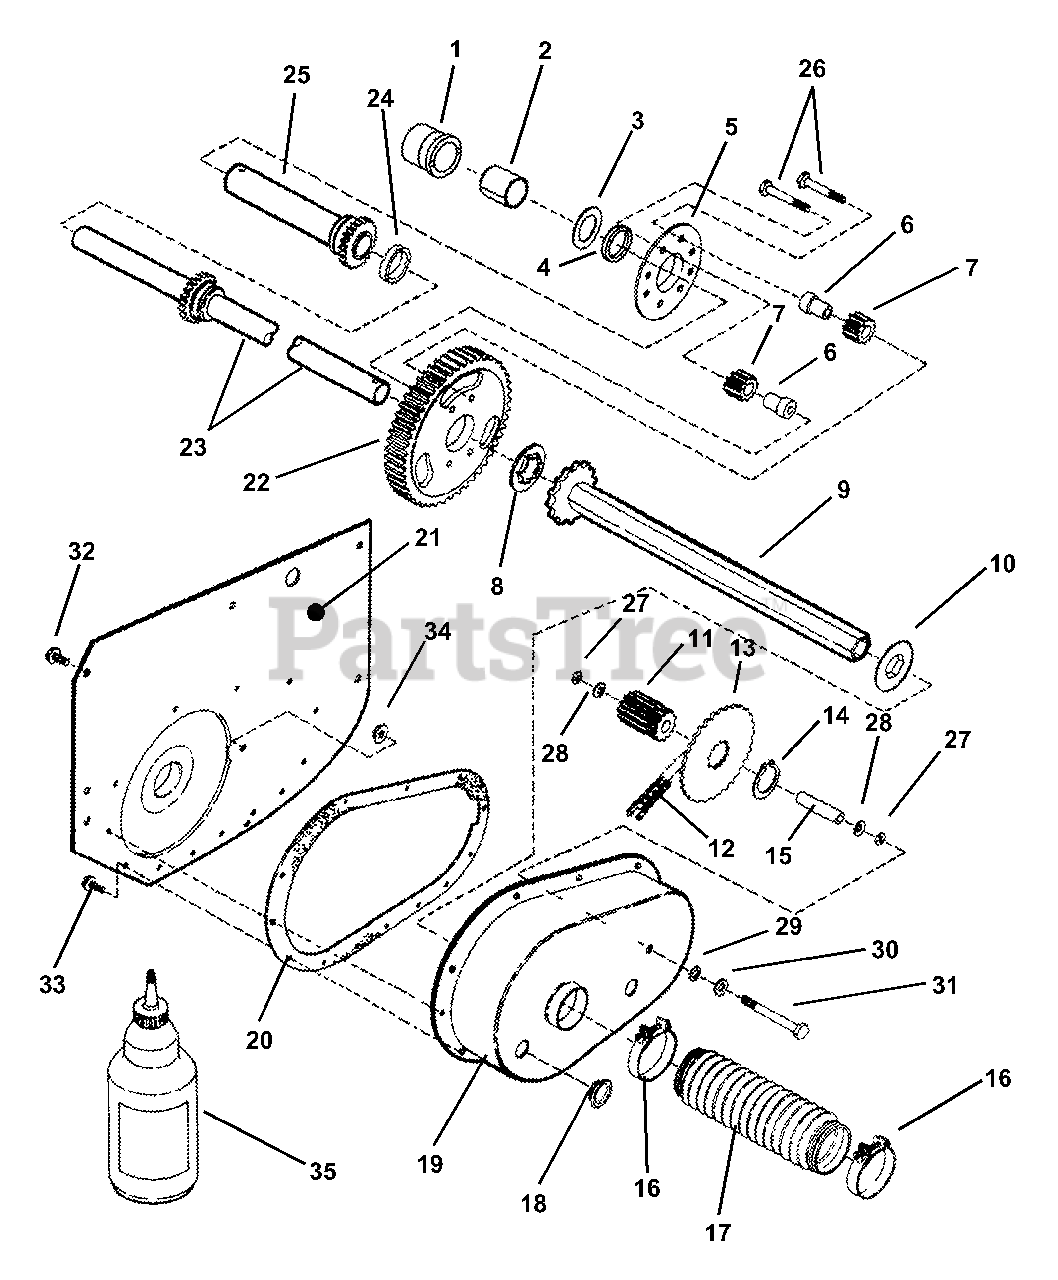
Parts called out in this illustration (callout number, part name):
1	BEARING, Axle
2	BEARING, DX
3	WASHER, Thrust
4	SPACER, Short Axle
5	PLATE, Differential
6	SPACER, Pinion
7	GEARS, Differential Pinion
8	WASHER, Thrust
9	ASSEMBLY, Drive Hex Tube
10	WASHER, Hex Insert
11	GEAR, 11 Teeth-10 Pitch
12	CHAIN, 46 Pitch (#35)
13	SPROCKET
14	RING, 1-13/16" External Retaining
15	SPACER
16	CLAMP, Boot
17	BOOT, Oil Seal
18	PLUG, Oil Fill & Check
19	CASE, Transmission
20	GASKET, Transmission Case
21	FENDER, Right Hand
22	GEAR, 63 Teeth-10 Pitch
23	AXLE, Long
24	SPACER
25	AXLE, Short
26	SCREW, 5/16-24 x 1-5/8" Hex Cap Special Lock
27	O-RING, 5/16"
28	WASHER, Belleville
29	WASHER, 5/16" External Tooth Lock
30	WASHER, 5/16" Flat
31	BOLT, 5/16-24 x 2-5/8" Idler
32	SCREW, 5/16-18 x 5/8" Hex Washer Self-Tap
33	SCREW, 1/4-20 x 5/8" Hex Washer Self-Tap
34	NUT, 5/16-24 Hex Flange Lock
35	GREASE, SNAPPER Transmission
